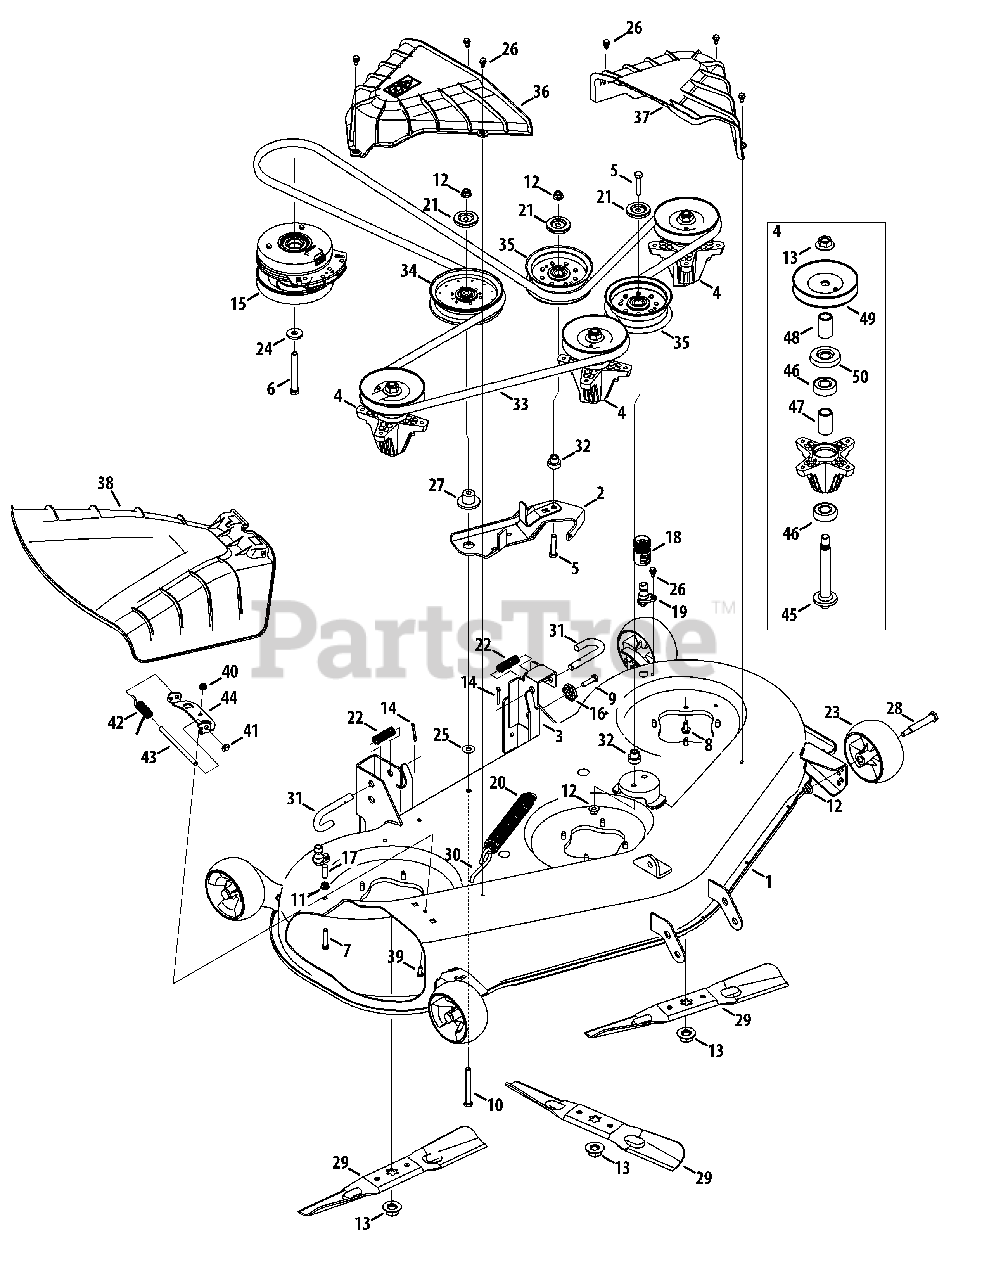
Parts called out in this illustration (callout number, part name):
1	50" Deck
2	Deck Idler Assembly
3	Deck Lift Bracket
4	Spindle Assembly
5	Hex Cap Screw, 3/8-16 x 1.75
6	Hex Cap Screw, 7/16-20 x 3.50
7	Hex Head Screw, 5/16-18 x 1.50
8	Hex Washer Screw, 5/16-18 x .750
9	Hex Flange Screw, 3/8-16
10	Hex Bolt 3/8-16 x 3.25"
11	Flange Lock Nut, 5/16-18
12	Flange Lock Nut, 3/8-16
13	Hex Flange Nut, 5/8-18
14	Cotter Pin, 5/32 x 1.25
15	Clutch, Electric PTO
16	Deck Adjustment Gear
17	Vinyl Cap, .29 x 1.00
18	Water Nozzle Adapter
19	Deck Wash Nozzle
20	Extension Spring, 1.25 OD x 1.751
21	Pulley Cap
22	Compression Spring, .66 x 1.9
23	Deck Ball Wheel, 5.0
24	Flat Washer, .450 x 1.25 x .164
25	Flat Washer, .385 x 1.0 x .030
26	Shoulder Screw, 1/4-20 x 0.50
27	Shoulder Spacer
28	Shoulder Screw, .5 x 2.5 x 3/8-16
29	Blade, Cut, 17.27" 2-In-1
30	Deck Spring Rod
31	Deck Hanger Rod
32	Shoulder Spacer
33	V-Belt
34	Idler Pulley, 5.00 Dia.
35	Pulley, Idler, 4.50" Dia.
36	Belt Cover, RH
37	Belt Cover, LH
38	Chute Deflector Assembly
39	Hex Cap Screw, 1/4-20 x .62
40	Nut, Flange Lock, 1/4-20, Nylon
41	Push Cap
42	Spring, Torsion, .440 ID x 1.75
43	Hinge Pin
45	Spindle Shaft, 6.11 Long
46	Ball Bearing
47	Spacer, .792 x 1.060 x 1.860
48	Spacer, .792 x 1.060 x 1.782
49	Deck Pulley
50	Bearing Shield
